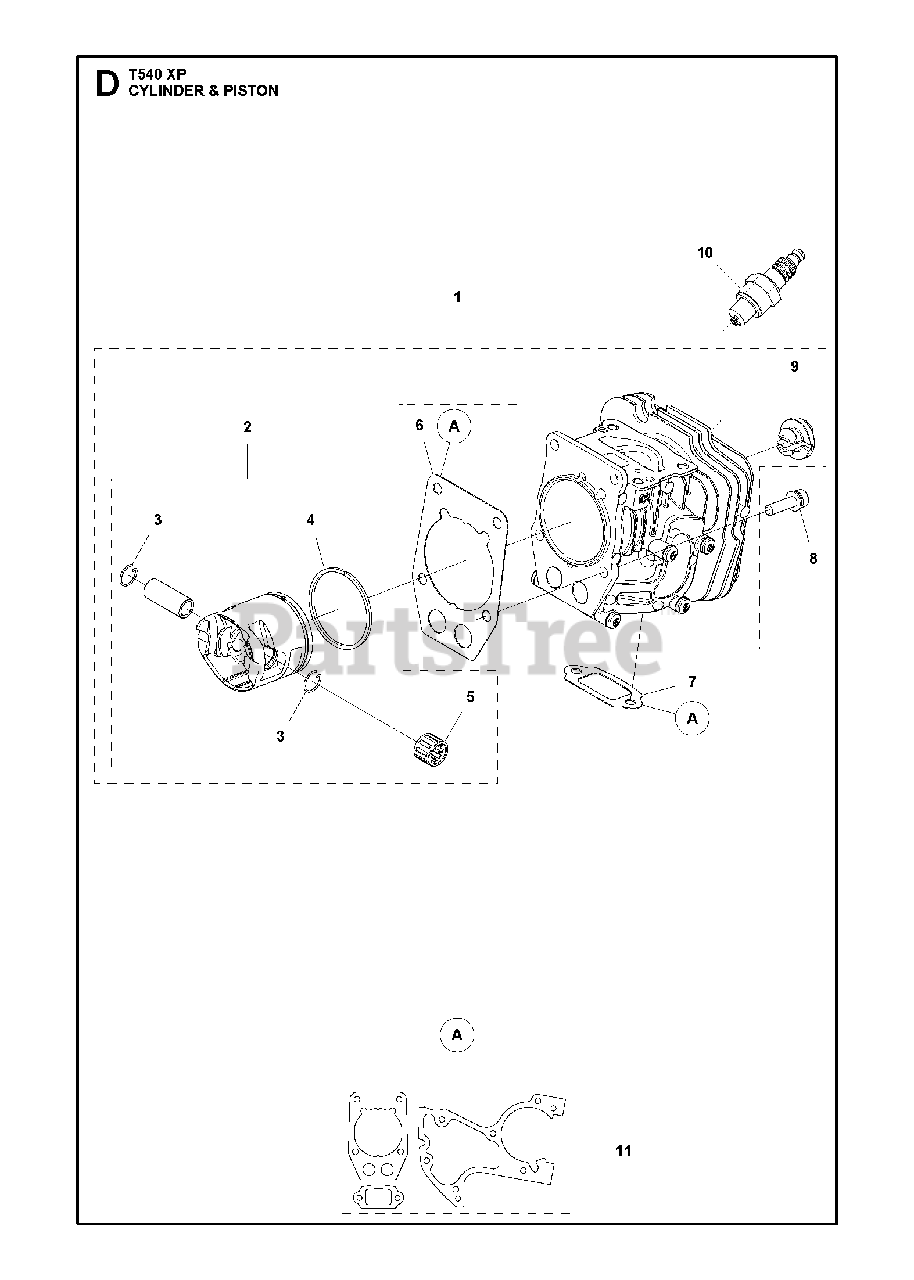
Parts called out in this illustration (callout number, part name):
1	CYLINDER-PISTON ASSY
1	CYLINDER ASSY
2	PISTON ASSY
3	LOCKING RING
4	PISTON RING
5	NEEDLE BEARING
6	GASKET
7	GASKET
8	SCREW ITXSCM
9	SUPPORT
10	CMR6H NGK SPARK PLUG
11	GASKET KIT
